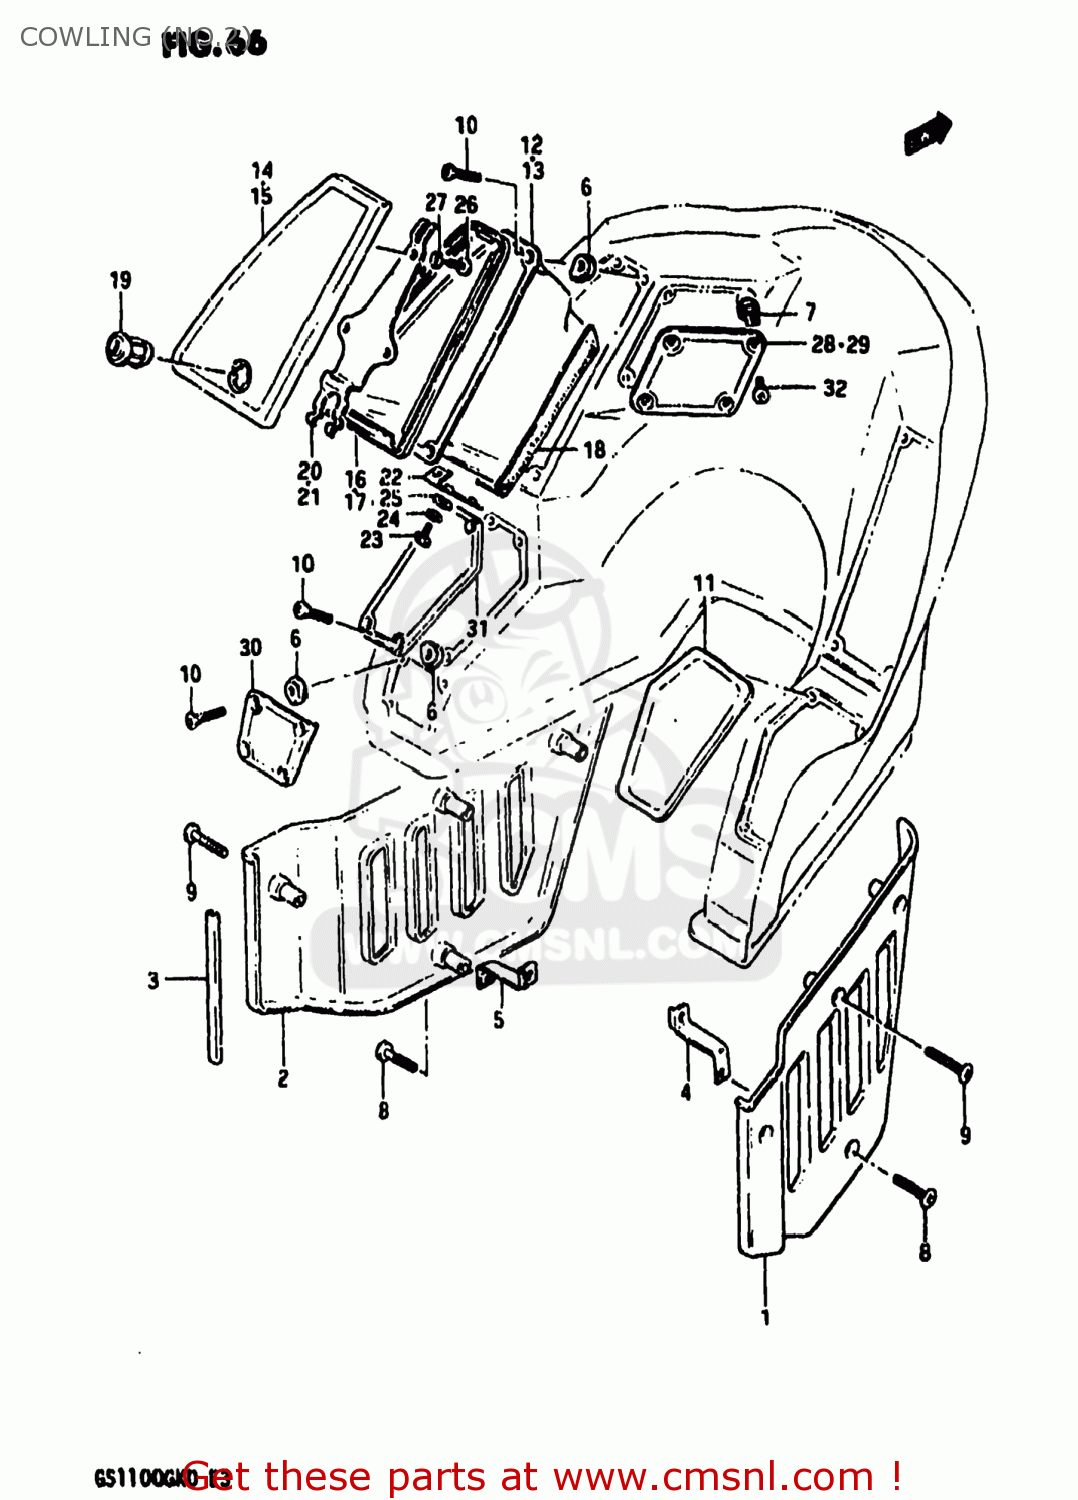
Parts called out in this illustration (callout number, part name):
1	COVER,COWLING,LOWER,RIGHT
2	COVER,COWLING,LEFT
3	MOLDING,COWLING LOWER COVER
4	BRACKET
5	BRACKET
6	PLATE,COVER FITTING NO
7	PLATE,COVER FITTING NO
8	SCREW
9	SCREW
10	SCREW (5X16)
11	GLOVE BOX,COWLING
12	CONSOLE BOX,RIGHT
13	CONSOLE BOX,LEFT
14	LID,CONSOLE BOX,RIGHT
15	LID,CONSOLE BOX,LEFT
16	CUSHION,CONSOLE BOX
17	CUSHION,CONSOLE BOX,LEFT
18	CUSHION CONSOLE BOX
19	LOCK,CONSOLE BOX
20	PLATE,LOCK HOLDER,RIGHT
21	PLATE,LOCK HOLDER,LEFT
22	PLATE,LOCK HOLDER SUPPORT
23	BOLT
24	LOCK WASHER
25	WASHER
26	SCREW
27	WASHER
28	COVER,SPEAKER,RIGHT
29	COVER,SPEAKER,LEFT
30	COVER,CB CONTROLER
31	COVER,RADIO CASE,LEFT
32	SCREW (5X30)
